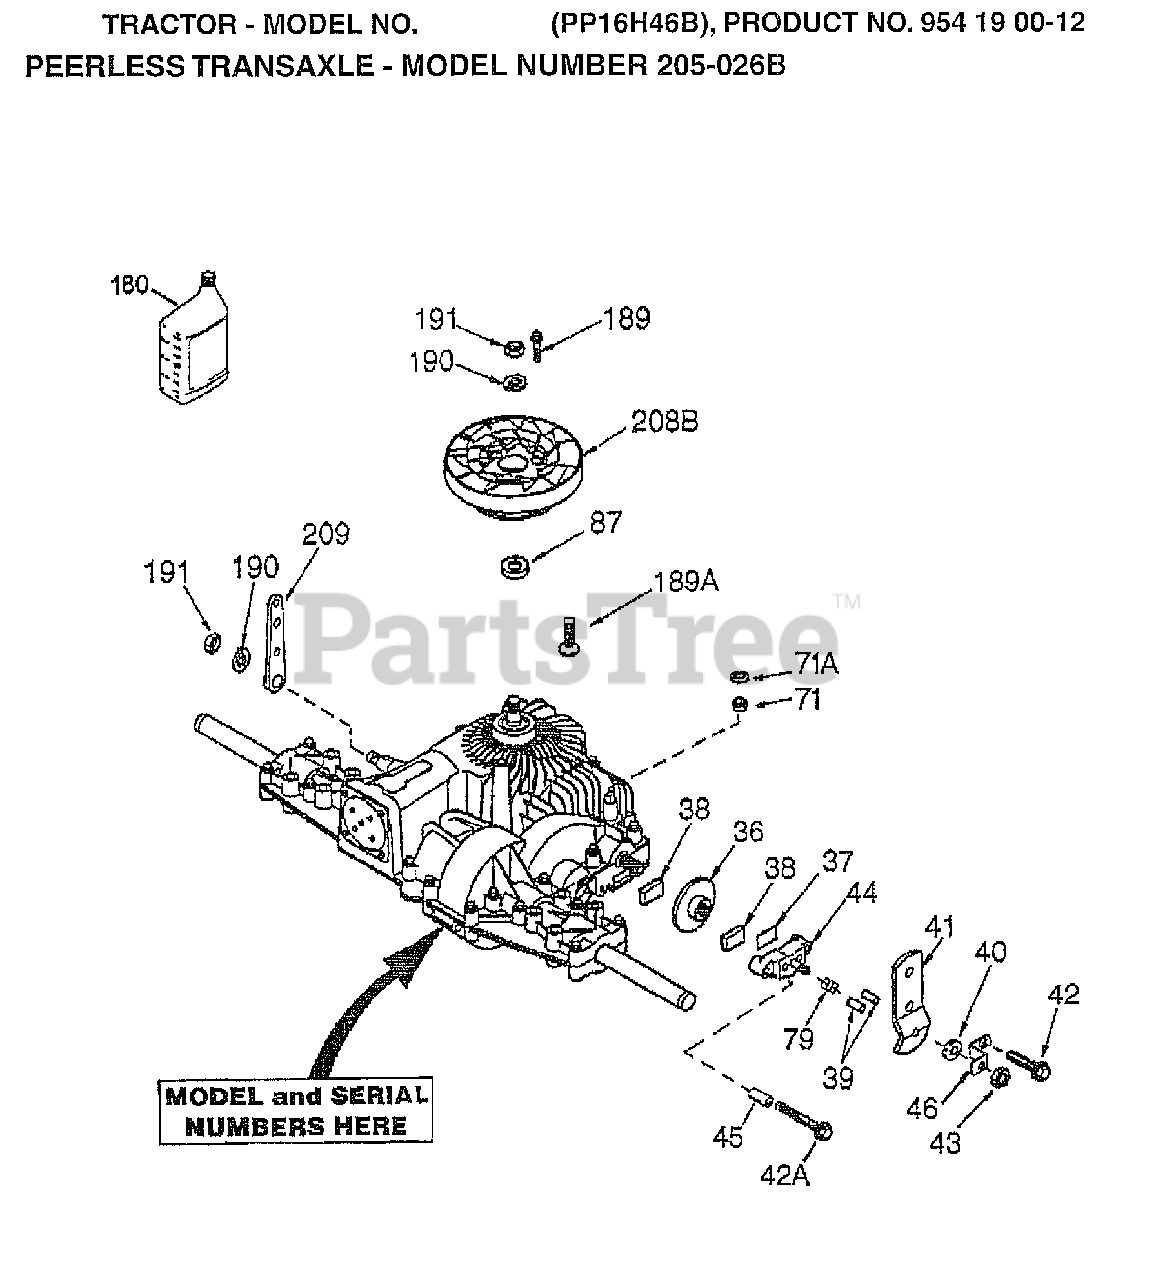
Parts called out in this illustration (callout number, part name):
37	PLATE BRAKE PAD
41	BRAKE LEVER
42	SCREW, 1/4-20 X 1-1/4
42A	SCREW, 1/4-20 X 2-1/4
43	LOCKNUT 5/16-24
44	HOLDER BRAKE PAD
46	BRAKE LEVER BRACKET
71	SEAL SQUARE CUT
180	GEAR OIL 80W90
189	DRIVE SCREW
208B	FAN/COUPLING
209	CONTROL LEVER
